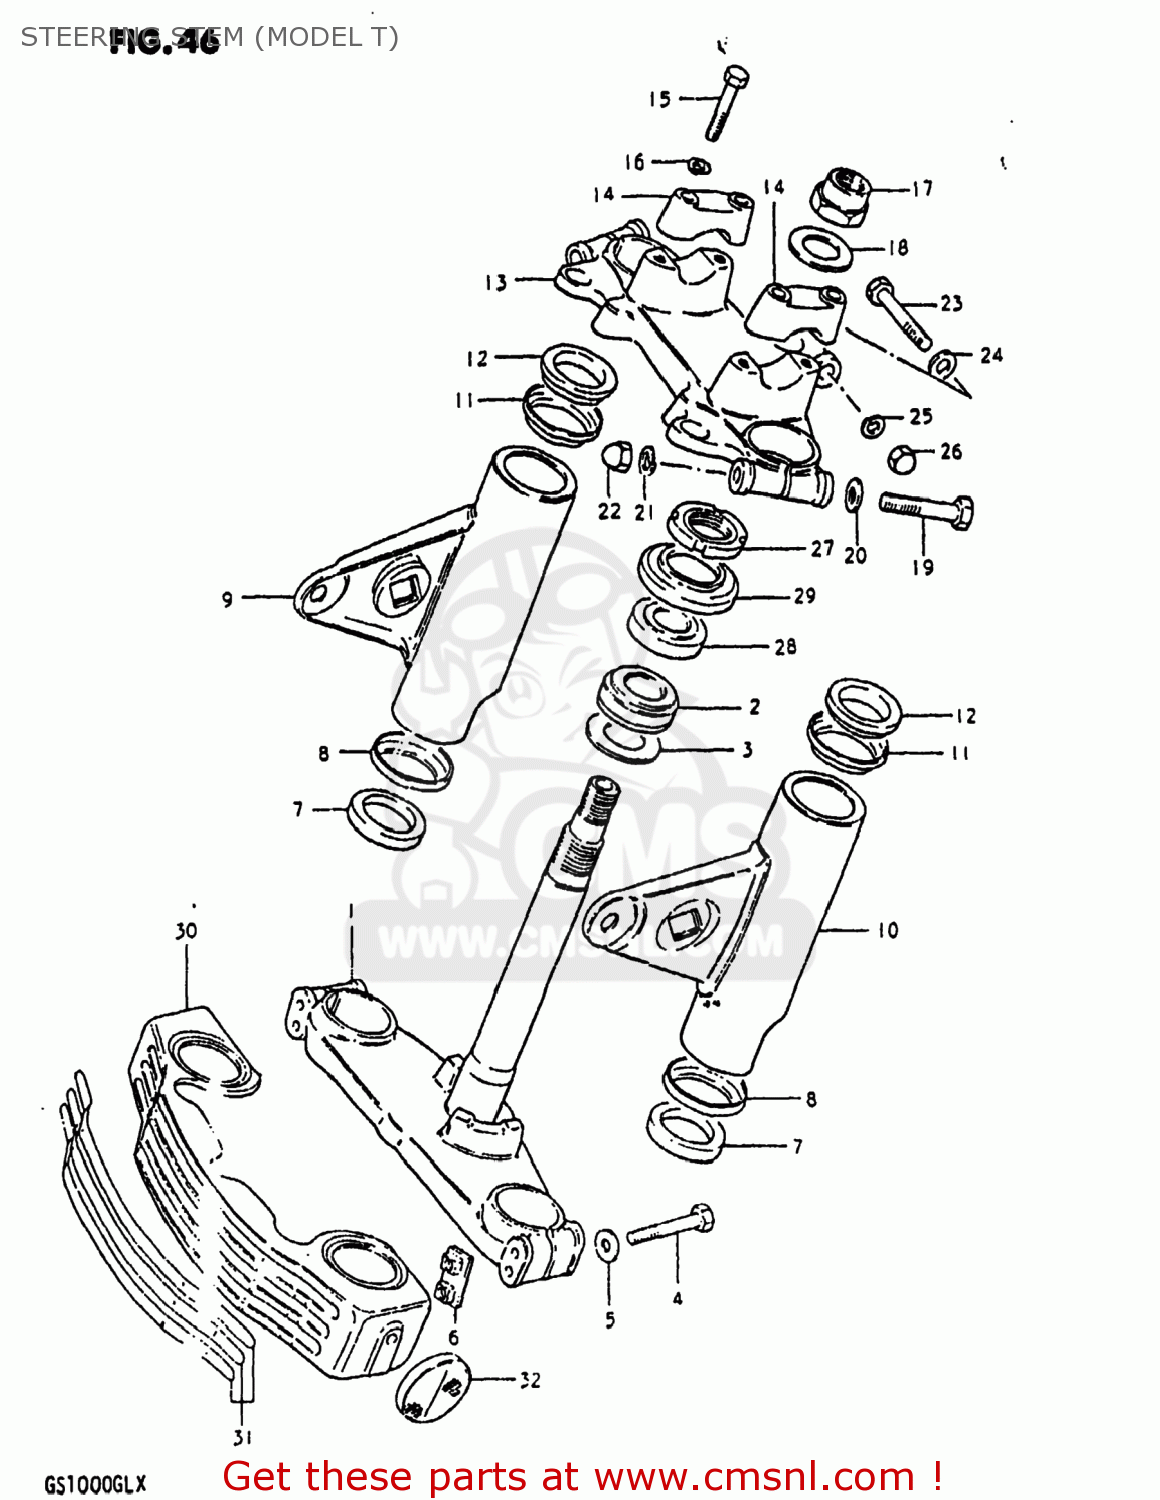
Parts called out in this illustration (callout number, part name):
1	STEM,STEERING
2	BEARING
3	WASHER,THRUST
4	BOLT 8X55
5	WASHER
6	NUT,FR FORK INNER TUBE
7	CUSHION,HEADLAMP BRACKET
8	SEAT,HEAD LAMP BRACKET
9	BRACKET,HEADLAMP,RIGHT
10	BRACKET,HEADLAMP,LEFT
12	CUSHION,HEADLAMP BRACKET
13	HEAD,STEERING STEM
14	HOLDER,HANDLE(BLACK)
15	BOLT
16	LOCK WASHER
17	NUT,FR FORK UPR BRACKET
18	WASHER
19	BOLT 10X55
20	WASHER
21	LOCK WASHER
22	NUT 10MM
23	BOLT 8X50
24	WASHER
25	WASHER,LOCK,8.
26	NUT,M8X1.25X12
27	NUT,STEERING STEM(25X44X10)
28	TAPER,ROLLER BEARING
29	DUST SEAL,STEERING,UPPER
30	COVER,FRONT FORK
31	TAPE SET,FRONT FORK COVER
32	REFLEX REFLECTOR,RR
